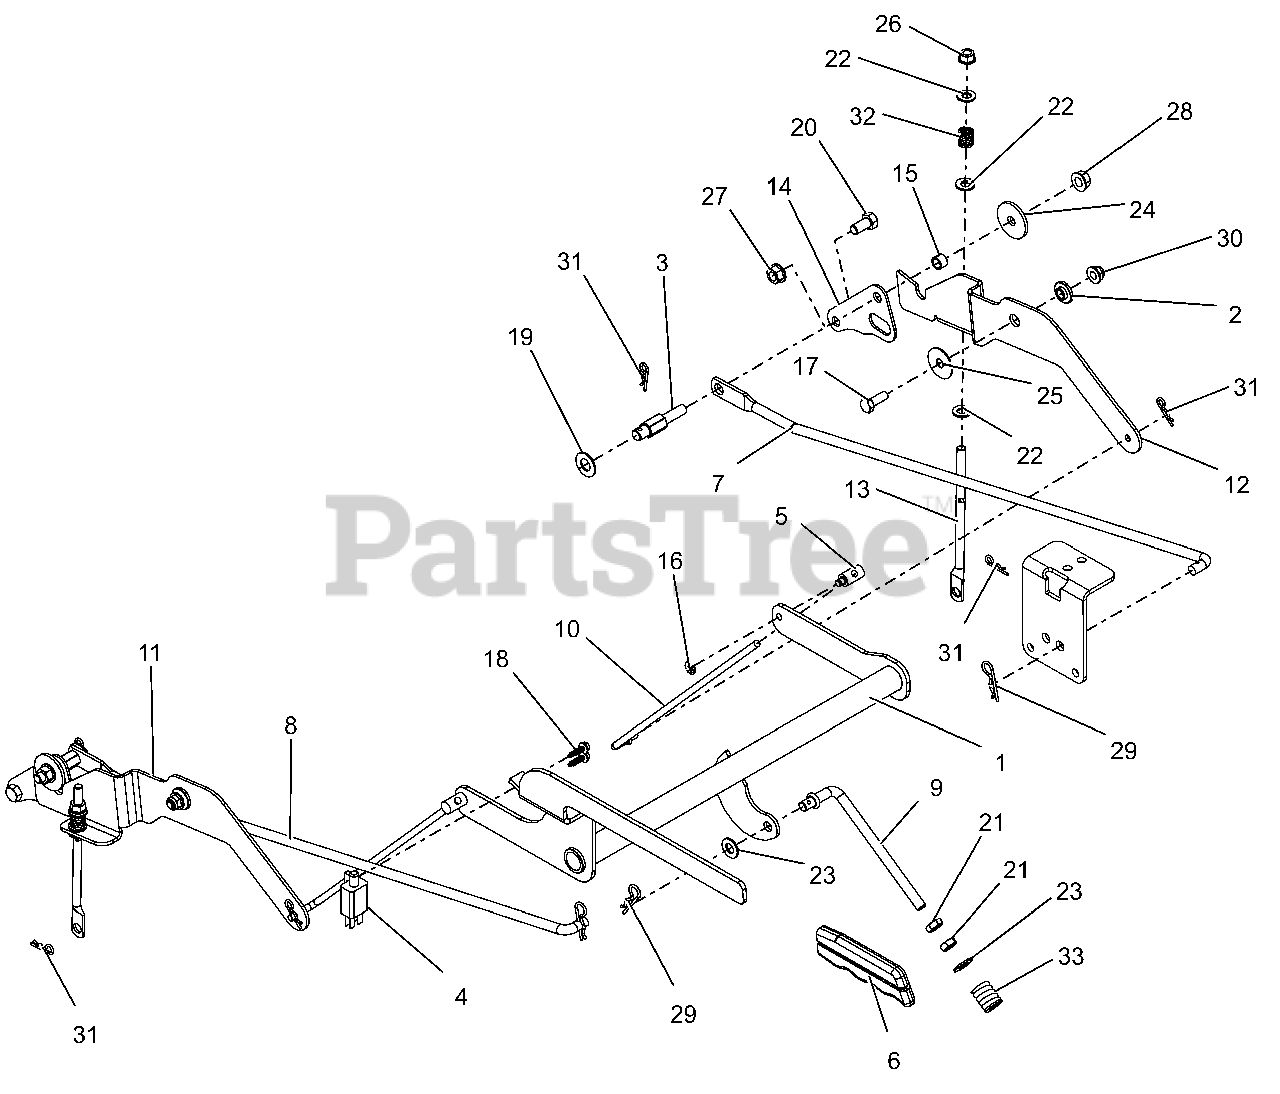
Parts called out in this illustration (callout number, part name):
1	WLDMT, BRAKE LEVER
2	BSHG, FLG .325X.499X.26X.88
3	POST, STEERING LINK MOUNTING
4	SWITCH- DOUBLE POLE N.O./N.O.
5	TRUNION, 1/4-20
6	GRIP, PARKING BRAKE (YELLOW)
7	ROD, STEERING LINKAGE LH
8	LINKAGE, STEERING - RH
9	LINK, OVER CENTER, PARKING BRK
10	ROD, PARK BRAKE
11	INTERLOCK, RH BRAKE LINK
12	INTERLOCK, LH BRAKE LINK
13	LINK, TRANSAXLE BRAKE
14	PLATE, TRANSAXLE ADAPTOR
15	SPCR, SLV .385X.500X.350
16	RG-RTNG-EXT .250X.025
17	BLT, HEX .31-18X.875 G5 ZCC
18	SCR, PLASTITE-HWH 0.2 X 0.75 ZC120
19	WSHR, FLT .505X1.00X.062 ZCC
20	BLT,HEX .38-16X.75 G5 ZCC
21	NUT-JAM .375-16 G2 ZCC
22	WSHR,FLT .344X.688X.065 ZCC
23	WSHR,FLT .406X.812X.065 ZCC
24	WSHR, FLT .380X1.50X.125 ZCC
25	WSHR, FLT .347X1.254X.048 ZCC
26	NUT,LK-CTR-FLG .31-18 GF ZCC
27	NUT-LK-TOP-FLG .38-16 ZC120
28	NUT-LK-CTR-FLG .375-16 GF ZCC
29	PIN, HAIR .09 X 1.50 ZCC
30	NUT,NYL-FLG .31-18 GF ZCC
31	PIN, HAIR #213 .08X1.19 ZCC
32	SPRING, COMPRESSION
33	SG-COMP .187X.56X1.62
